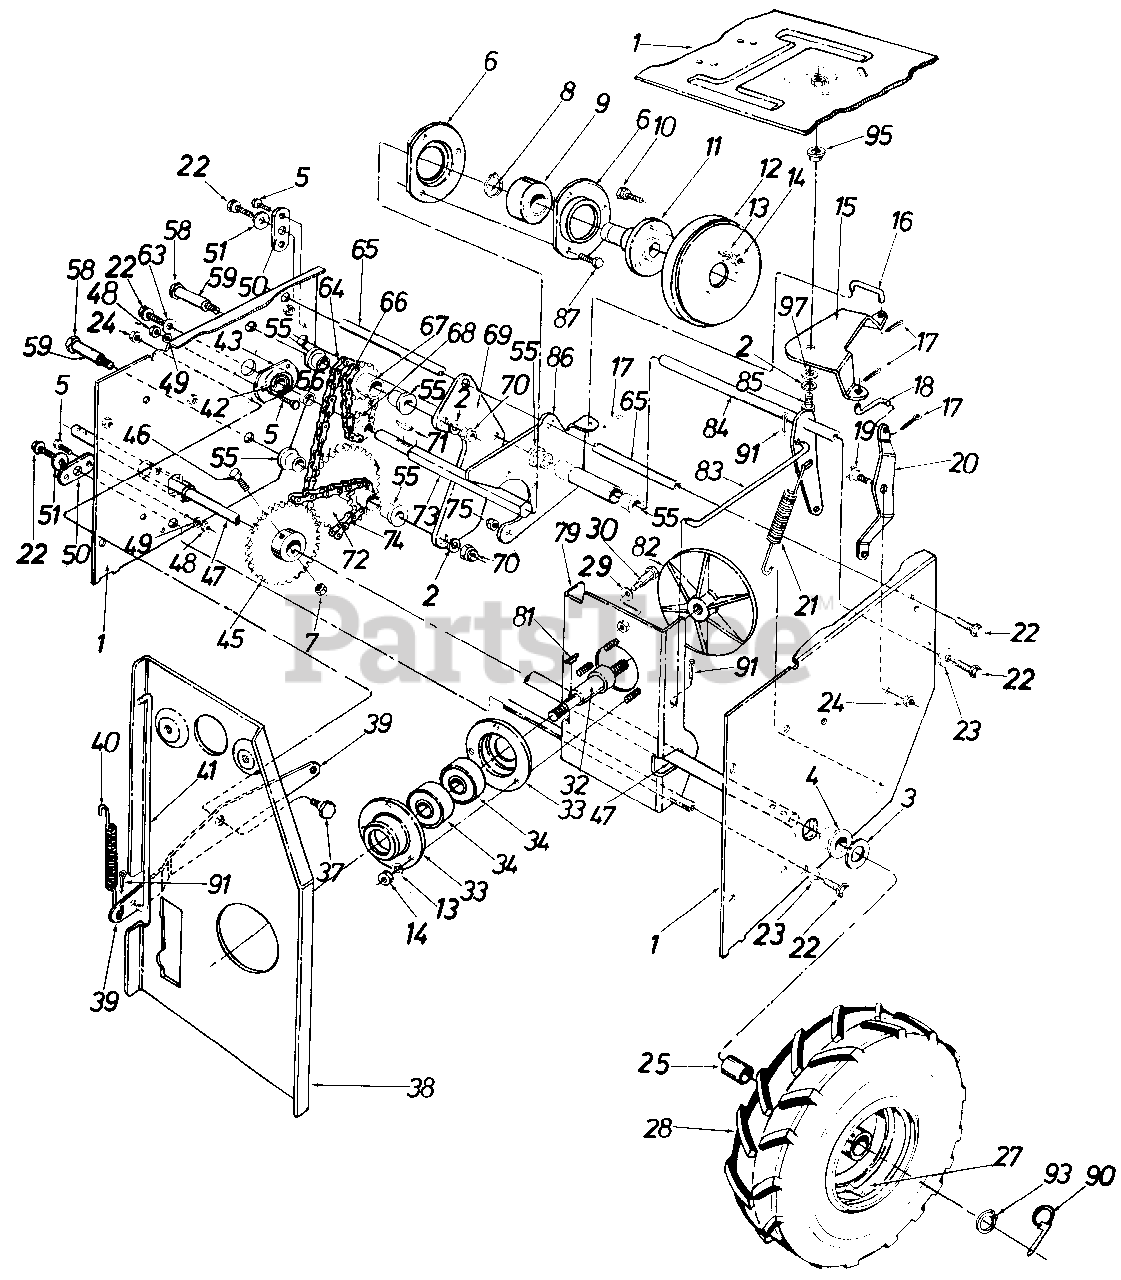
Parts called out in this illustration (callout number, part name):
1	Frame Ass'y.
2	L-Wash. 3/8" Scr.
3	Fl-Wash. 1.03" I.D. x 1.62" O.D. x .03
4	Flange Brg. 1.0" I.D.
5	Hex Bolt 1/4-20 x .62" Lg.
6	Bearing Housing
7	Hex L-Nut 5/16-24 Thd.
8	Snap Ring for 1.00" Dia. Shaft
9	Ball Brg. 25 mm x 52 mm x 15 mm
10	Hex Sems Scr. 5/16-18 x .75" Lg.
11	Friction Wheel Adapter
12	Friction Wheel Ass'y.
13	L-Wash. 5/16" Scr.
14	Hex Nut 5/16-18" Thd.
15	Sliding Linkage Brkt.
16	Sliding Rod - .31" Dia. x 2.00" Lg.
17	Cot. Pin 3/32" Dia. x .75" Lg.
18	Shifting Linkage Rod .31" Dia. x 2.25" Lg.
19	Shld. Scr. .625" Dia. x .170" Lg.
20	Shifting Linkage Brkt.
21	Extension Spring .73 O.D. x 4.31" Lg.
22	Hex L-Scr. 5/16-18 x .62" Lg.
23	Fl-Wash. .345 I.D. x .75 O.D. x .060
24	Hex Cent. L-Nut 3/8-16 Thd.
27	Wheel Rim Ass'y.
28	Wheel Ass'y. Comp. 16 x 4.5 - L.H.
29	Bell-Wash.
30	Shld. Scr.
32	Drive Plate Spindle
33	Bearing Housing
34	Ball Brg. .787 I.D. x 1.85 O.D. x .56
37	Shld. Scr. .625" Dia. x .170" Lg.
38	Engine Brkt. Ass'y.
39	Auger Clutch Brkt.
40	Extension Spring .38 O.D. x 3.18" Lg.
41	Auger Clutch Rod .31" Dia. x 10.62" Lg.
42	Ball Bearing
43	Bearing Housing
45	28 Tooth Sprocket - Hub Ass'y.
46	Hex Scr. 5/16-24 x 1.75" Lg.
47	Axle - Free Wheeling
48	Hex Nut 1/4-20 Thd.
49	L-Wash. 1/4" Scr.
50	Pivot Axle Brkt.
51	Fl-Wash. .345" I.D. x .75" O.D. x .060
55	Flange Brg. - .630" I.D.
56	Spacer .51" I.D. x .69" O.D. x .44
58	Hex Scr. 3/8-24 x 2.75" Lg.
59	Sprocket Hub Tubing 1.900" Lg.
63	Bell-Wash. .345" I.D. x .88 O.D. x .060
64	#41 Chain - 1/2" Pitch x 43 Links
65	Sliding Support Axle
66	#41 Chain 1/2" Pitch x 19 Links
67	9 and 14 Teeth Sprocket Hub Ass'y.
68	8 Teeth Sprocket
71	#9 Hi-Pro Key 3/32 x 5/8" Dia.
72	9 and 32 Teeth Sprocket Hub Ass'y.
73	Hex Shaft
74	#420 Chain - 1/2" Pitch x 37 Links
75	Hex Ins. Jam L-Nut 1/4-28"
82	Aluminum Drive Plate
83	Drive Clutch Rod .31" Dia. x 7.38" Lg.
84	Drive Clutch Brkt. Ass'y.
85	Hex Scr. 3/8-16 x 1.00" Lg.
86	Sliding Brkt. Ass'y.
87	Hex Scr. 1/4-28 x .62" Lg.
90	Klick Pin
91	Internal Cot. Pin 5/16 Dia.
93	Snap Ring 1.0" Shaft
95	Shld. Spacer 5/8" I.D.
